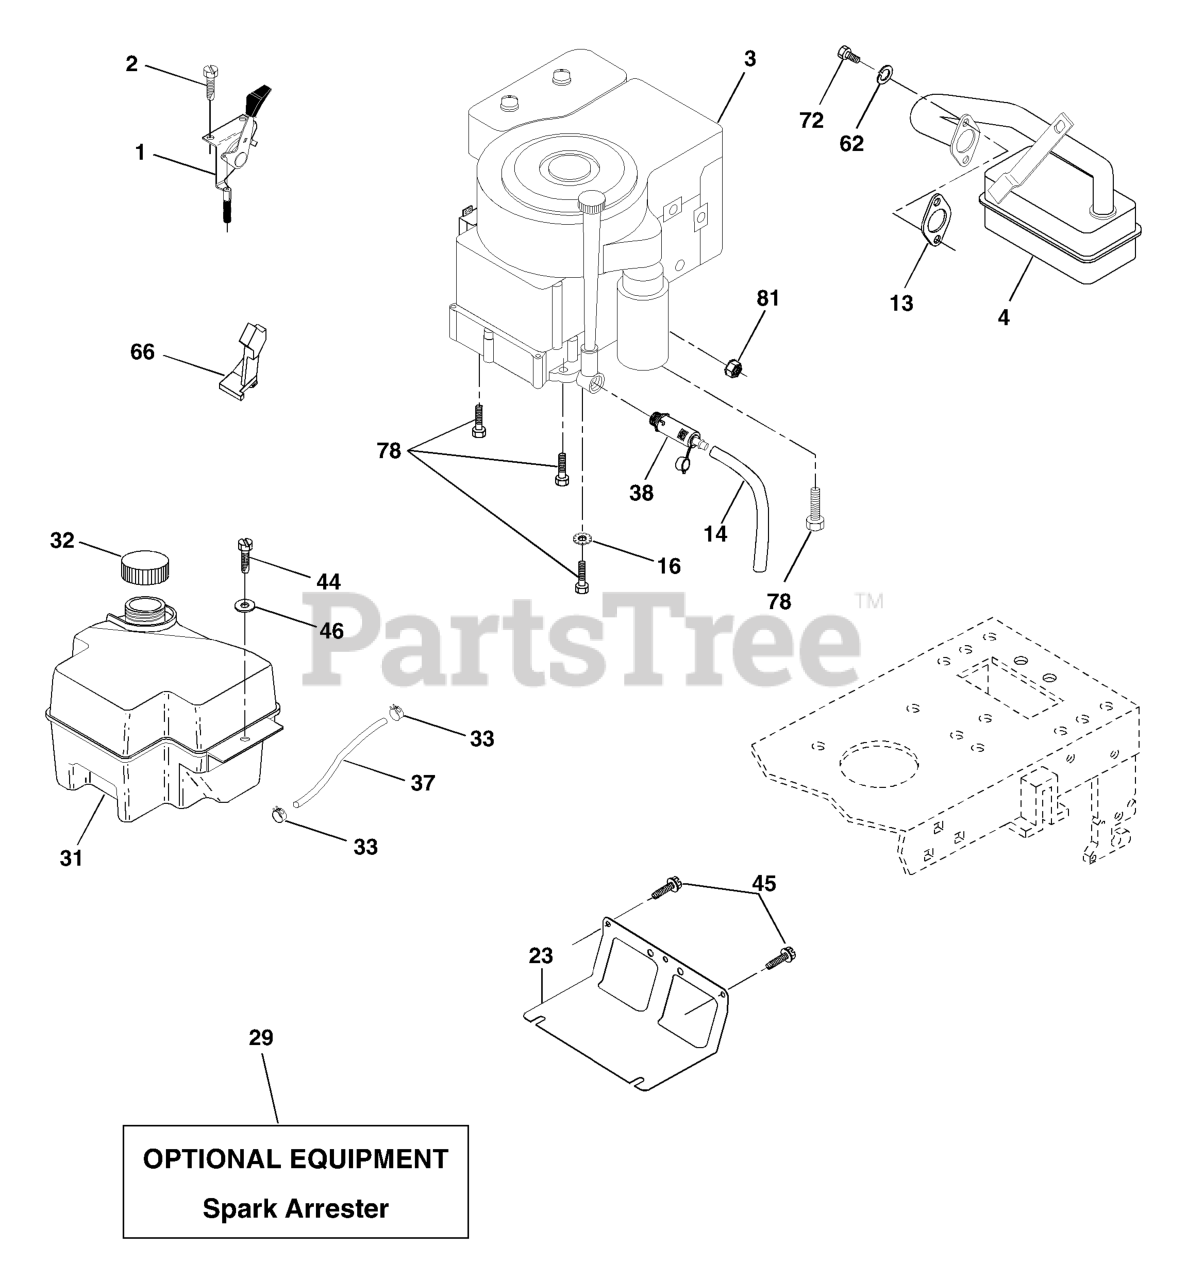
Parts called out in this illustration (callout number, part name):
1	THROTTLE.CONTROL.CABLE.BLACK
2	SCREW LT
4	MUFFLER.SINGLE.B&S.10-12HP
13	REPL BY 532 27 22-93
14	TUBE, DRAIN OIL ASM.
16	LOCKWASHER
23	SHIELD.BROWNING.DBR.GUARD
29	KIT.SPARK ARRESTOR 794945 B&S
31	TANK, 2GAL
32	FUEL CAP
33	HOSE CLAMP
37	LINE.FUEL.20
38	PLUG, OIL DRAIN EASY
44	SCREW HEXWSHR 1/4-20X3/4
45	SCREW, 3/8-16X3/4
46	WASHER
62	WASHER.LOCK.HVY.HLCL.SPR.5/16
66	STOP THROTTLE
72	SCREW
78	SCREW.3/8-16
81	NUT
